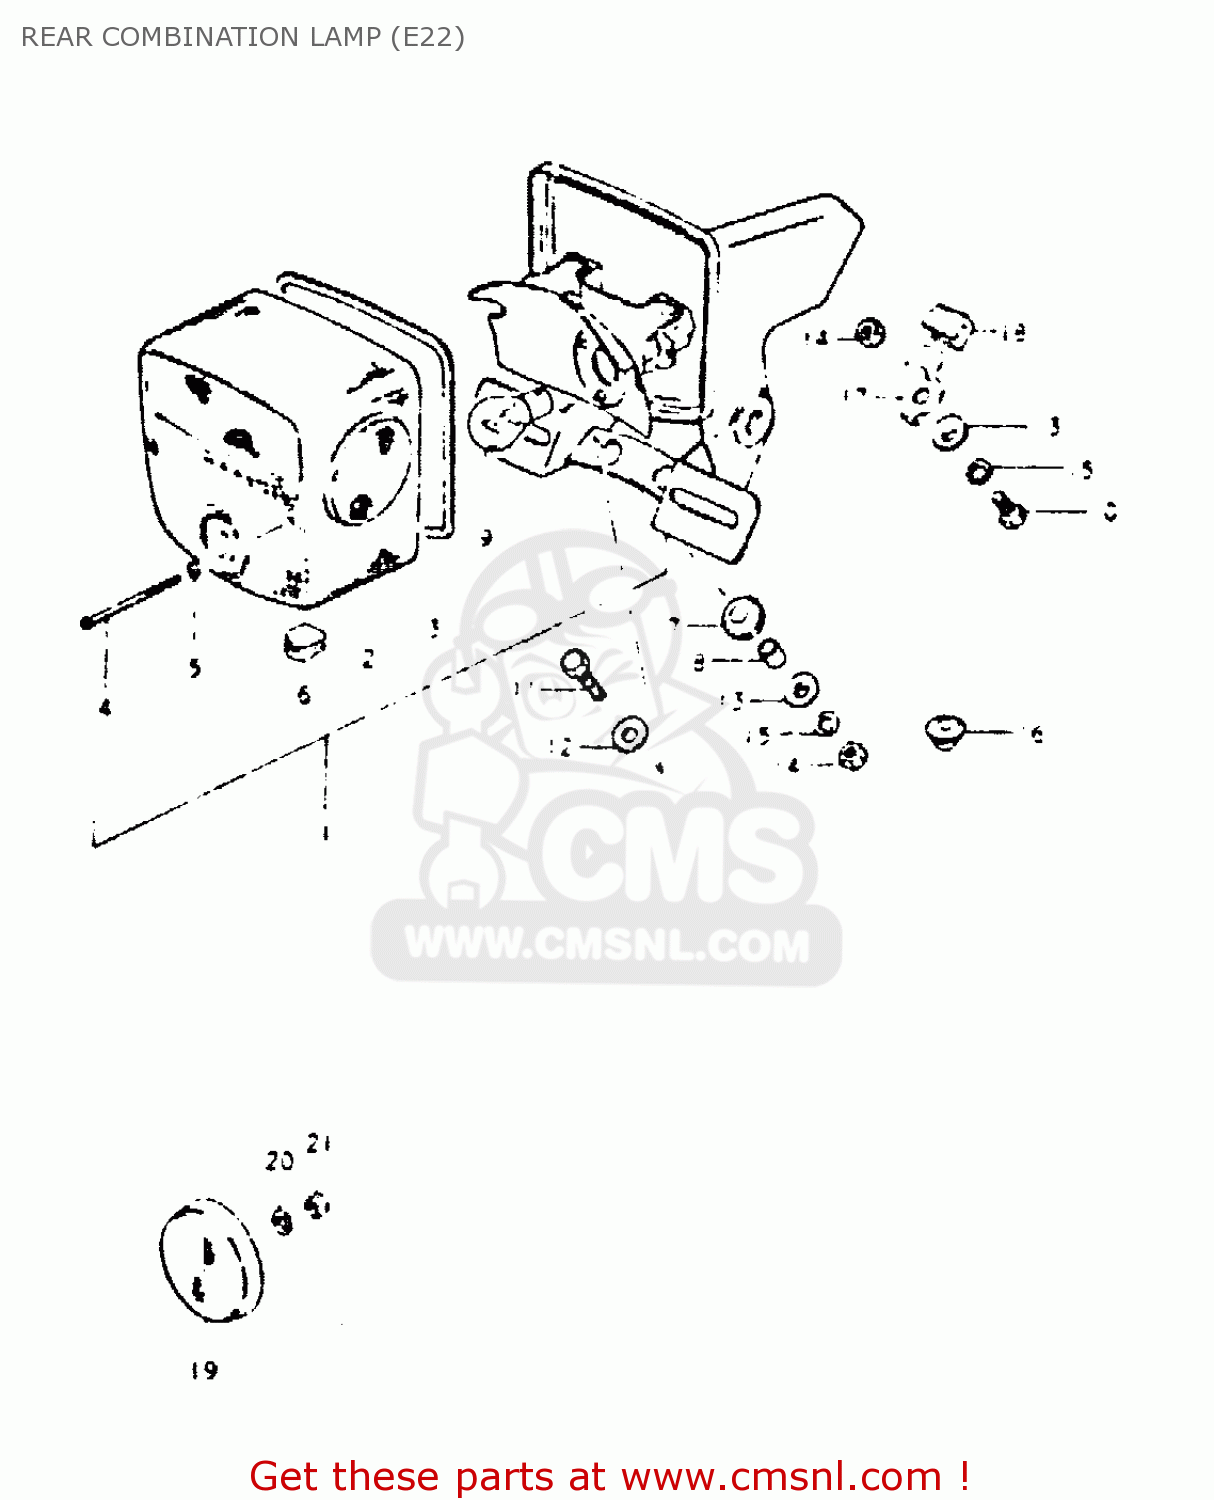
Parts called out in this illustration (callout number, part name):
1	LAMP ASSY, TAIL
2	LENS
3	GASKET (NAS)
4	SCREW (4X55)
5	GASKET (NAS)
6	GROMMET,REAR COMBINATION LAMP
7	CUSHION,REAR COMBINATION LAMP
8	SPACER
9	BULB (6V,21/5W)
10	BOLT
11	BOLT
12	WASHER (6.5X20X1.2)
13	WASHER
14	NUT
15	WASHER
16	GROMMET
17	PLATE
18	CUSHION
19	REFLECTOR,REFLEX
20	WASHER
21	NUT
